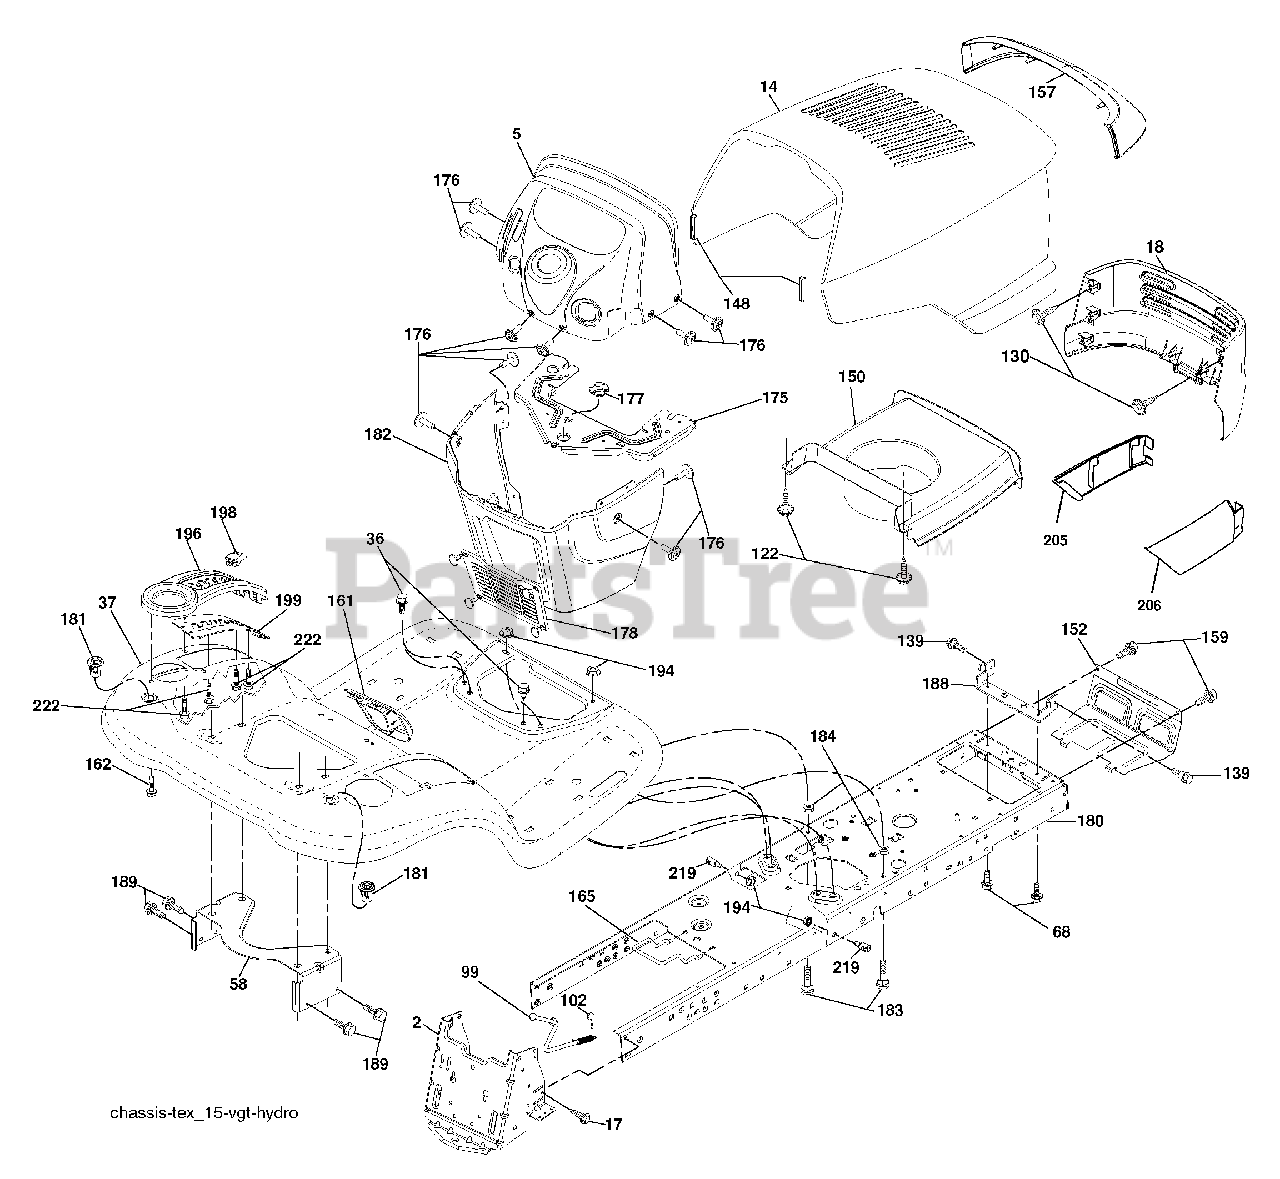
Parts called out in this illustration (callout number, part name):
5	Dash
14	Hood
17	Screw 3/8-16 x .75
18	Grille
36	Screw 5/16-18 x 3/4
37	Fender
58	Bracket Fender
68	Screw Thdrol 5/16-18 x 1/2
99	Rod Bypass Asm.
102	Retainer Spring 1"
122	Screw WSHD Hex 10-32 x 5/8
130	Screw 10 x 3/4 Single Lead-Hex
139	Bolt Shoulder 5/16-18
148	Bumper
150	Duct Heat Hood
152	Shield Browning/Debris
157	Lens Bar
159	Screw Hexwsh Thdrol 3/8-16 x 3/4
161	Console Fuel Window
162	Screw Hex Wsh Hi-Lo 1/4 x 1/2
165	Bracket Support Tank
175	Crossmember
176	Screw #10-24 x 5/8 Rnd Qudrx
177	Bushing Steering
178	Cargo Asm. Net
181	Bushing Mtg. Fender Crgo.
182	Dash Lower
183	Bolt Fin Hex 5/16-18UNC x 1-1/4
184	Spacer Fender
188	Bracket Pickoff Hood
189	Screw 5/16-18 x 3/4
194	Nut Lock Hex Flange 5/16-18
196	Console Asm. Deck Lift
198	Indicator Deck Lift
199	Plate Deck Lift
205	Skirt Hood RH
206	Skirt Hood LH
219	Stud Fastener
222	Screw thd Roll 1/4-20 x 5/8
